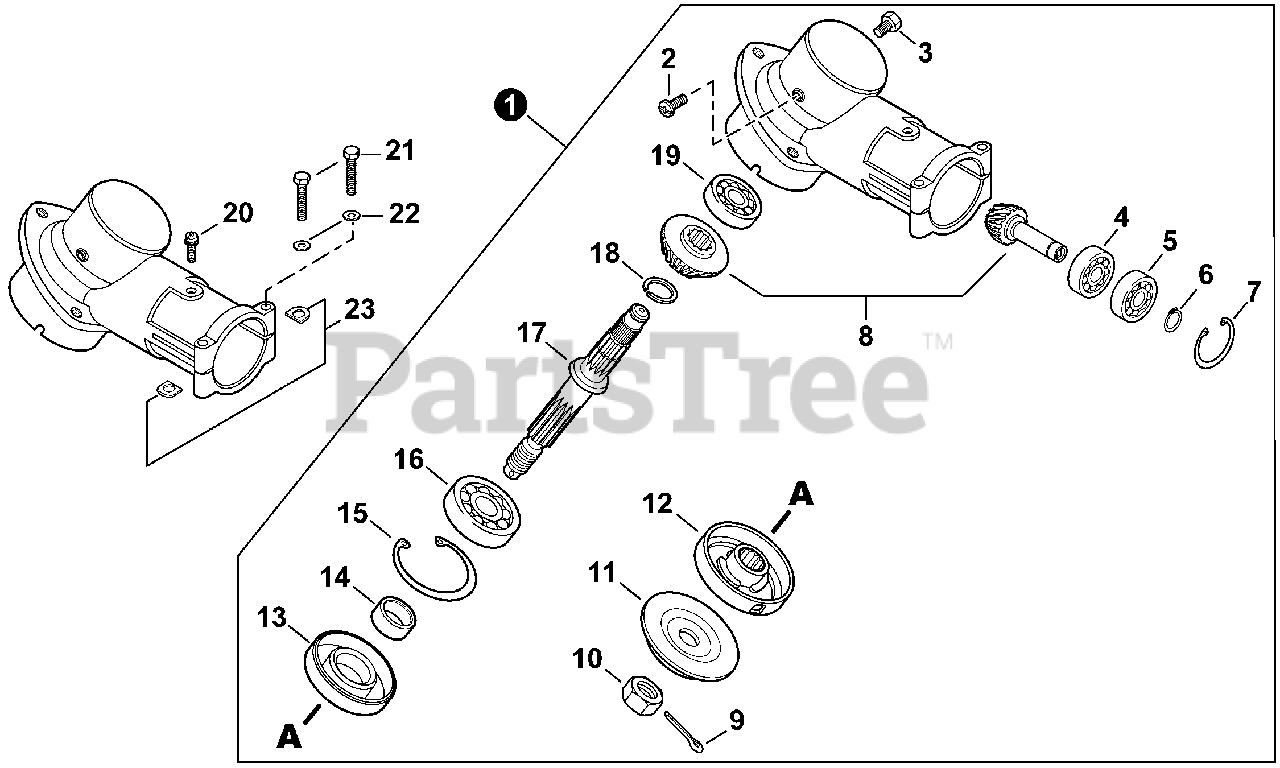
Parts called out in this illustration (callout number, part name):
1	GEAR CASE ASSY
2	SCREW 4×6
3	BOLT M8×8
4	BEARING, BALL 6001
5	BEARING, BALL 6001
6	RING, SNAP 12
7	RING, SNAP 28
8	GEAR SET
9	PIN, COTTER 2×22
11	PLATE, ADAPTOR - LOWER
12	PLATE, ADAPTOR - UPPER
13	SEAL, OIL 22
14	SPACER 11.8×15×9
15	RING, SNAP Ø32
16	BEARING, BALL 6201
17	SHAFT, GEAR
18	RING, SNAP Ø12
19	BEARING, BALL 6000
20	SCREW 5×10
21	BOLT 5×40
22	WASHER, FLAT 5.5×10×0.8
23	D-WASHER
